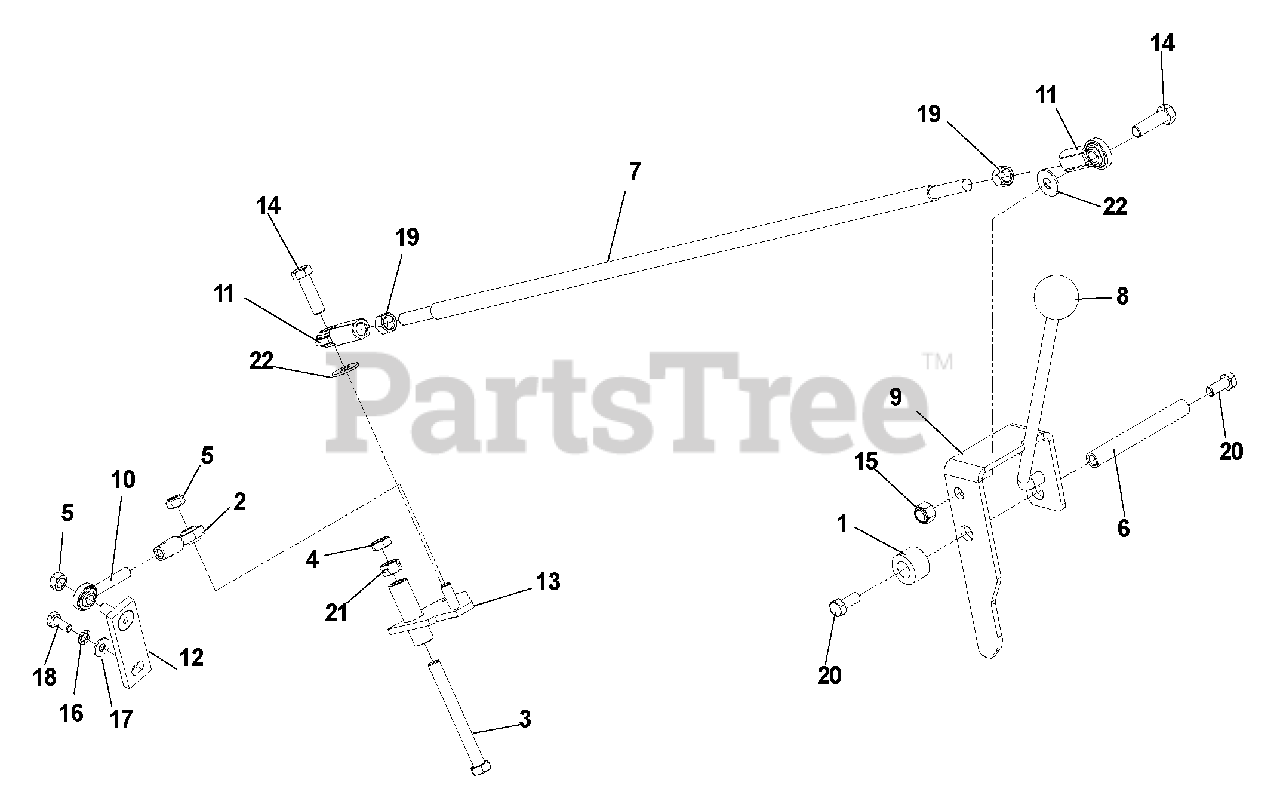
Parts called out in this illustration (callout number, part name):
2	END BALL, RIGHT
3	HCS, 3/8-16 X 3 1/2, GR8
4	NUT, 3/8-16, JAM
5	NUT, 5/16-24
6	SHAFT, SHIFT PIVOT
8	KNOB, SHIFT
9	SHIFT LEVER
10	ROD END, 5/16, MALE
11	ROD END, 3/8-24, FEMALE
12	SHIFT ARM, TRANSMISSION
13	SHIFT, BELL CRANK
14	HCS, 3/8-16 X 1 1/4, GR5
15	NUT, 3/8-16, NYLOC
16	WASHER, 1/4
17	WASHER, 1/4, SAE
18	HCS, 1/4-28 X 5/8, GR5
19	NUT, 3/8-24, GR2
20	HCS, 5/16-18 X 3/4, GR5
21	NUT, 3/8-16, CENTERLOCK
22	WASHER, 5/16
